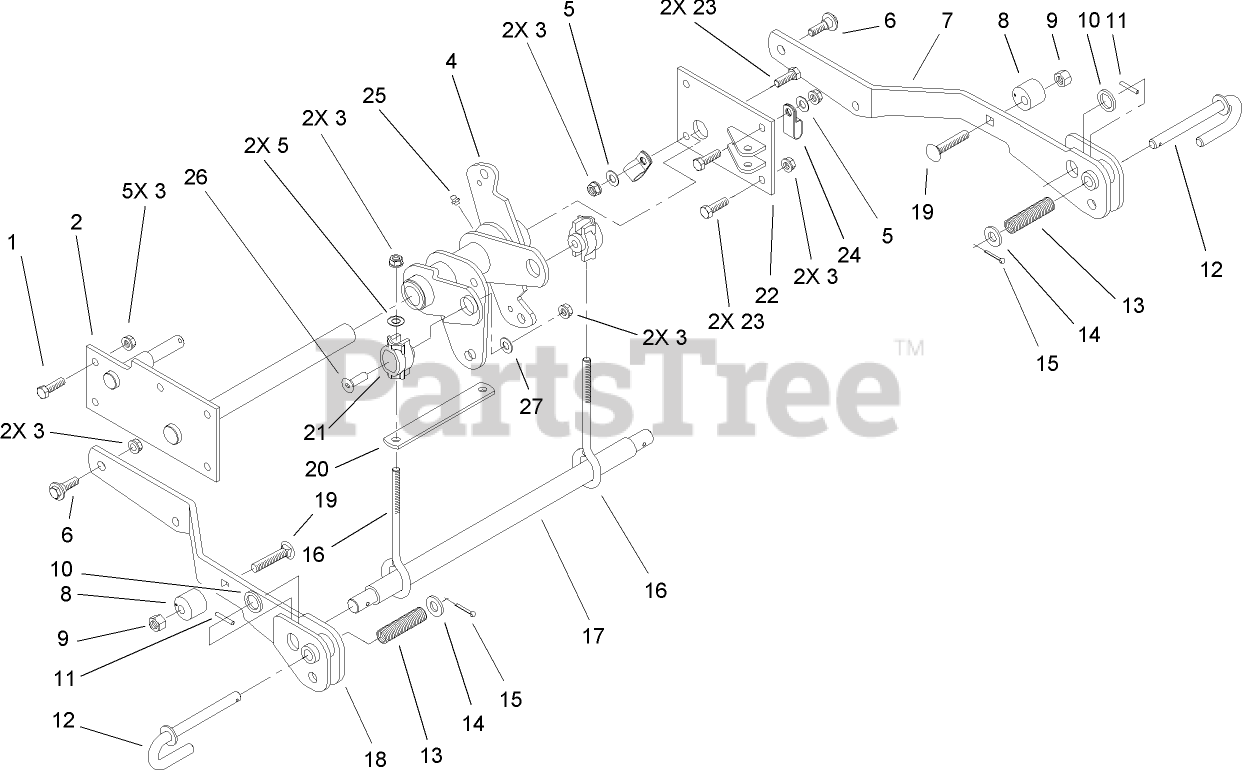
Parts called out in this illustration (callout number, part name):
1	SCREW-HH
2	SUPPORT-LIFT, DECK
3	NUT-LOCK, NI
4	BELLCRANK AND BUSHING ASM
5	WASHER-FLAT
6	SCREW-SHOULDER, HWH
7	ARM-LIFT, LH
8	STOP-LIFT, ADJ.
9	NUT-LOCK, NI
10	WASHER-FLAT
11	PIN-ROLL
12	PIN - J
13	SPRING-COMPRESSION
14	WASHER-FLAT
15	PIN-COTTER
16	ROD-LIFT
17	BAR-LIFT
18	ARM-LIFT, RH
19	SCREW-CARR
20	SPACER-STRAP
21	SLEEVE-LIFT
22	SUPPORT-CYLINDER
23	SCREW-HH
24	CLAMP-TUBE
25	FITTING-GREASE
26	SCREW-HSFH
27	WASHER-FLAT
